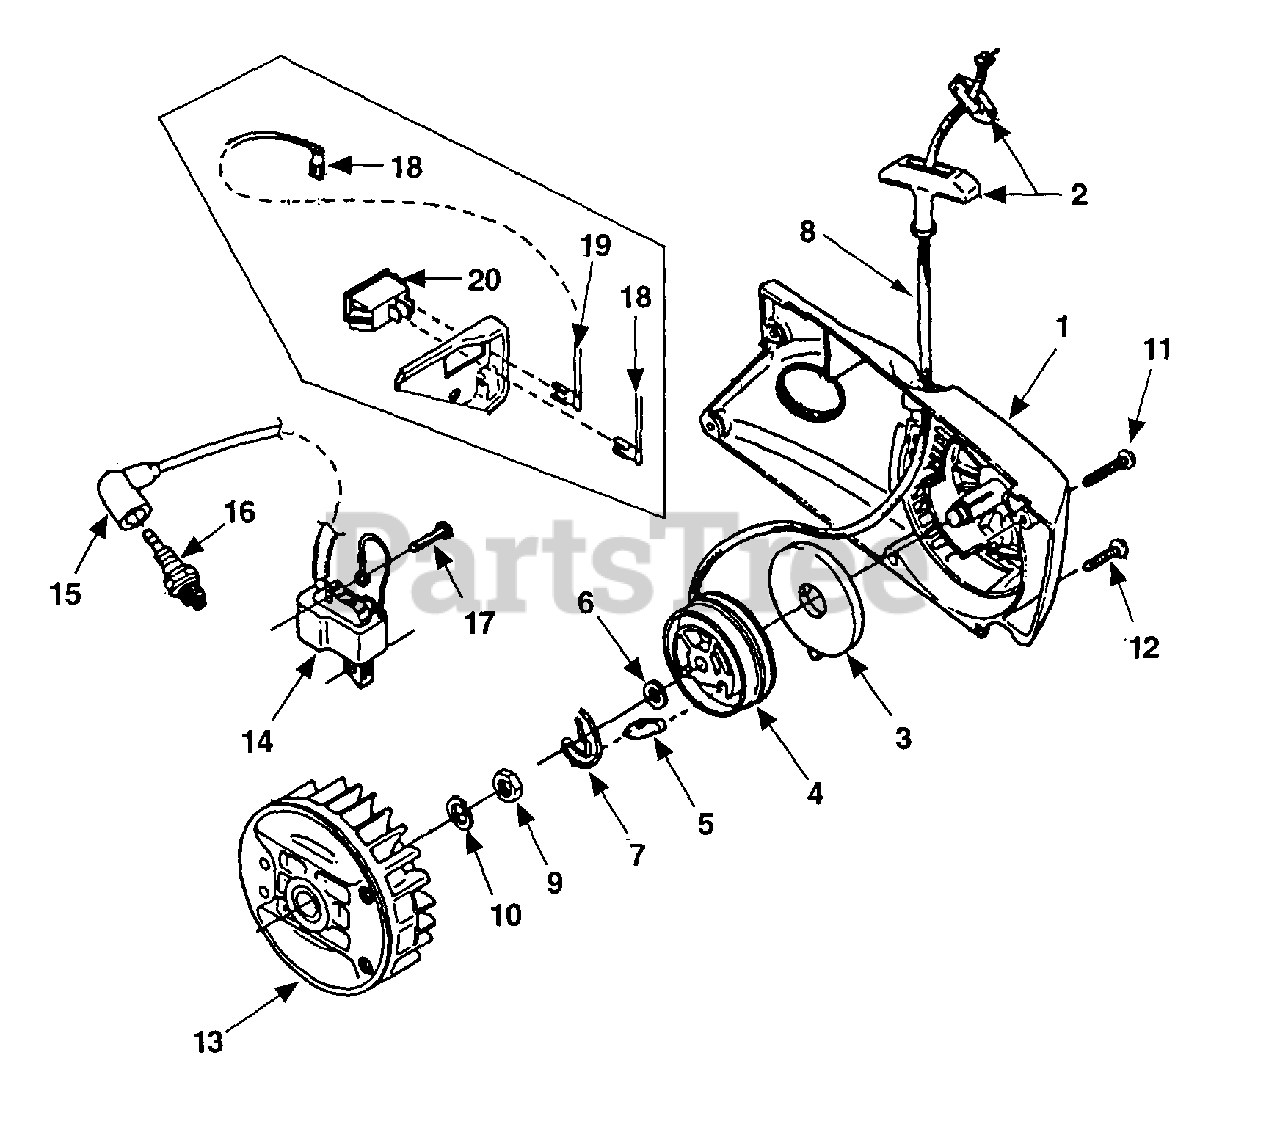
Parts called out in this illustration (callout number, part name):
1	STARTER (Complete)
2	GRIP-Starter (w/insert)
3	SPRING & CONTAINER
4	PULLEY ASSEMBLY
5	WASHER-Thrust
6	PAWL-Starter
7	CLIP-Retainer
8	ROPE-Starter (45")
9	NUT-Jam (3/8 - 24)
10	WASHER-Lock (3/8")
11	SCREW-Truss Hd. (10-24 x 1 1/4")
12	SCREW (10-24 x 3/4")
14	IGNITION MODULE
15	SPARK PLUG BOOT KIT
16	SPARK PLUG (RCJ6Y) (Resistor)
17	SCREW-Pan Hd (8-32 x 5/8")
18	GROUND WIRE
19	IGNITION GROUND WIRE
20	SWITCH
